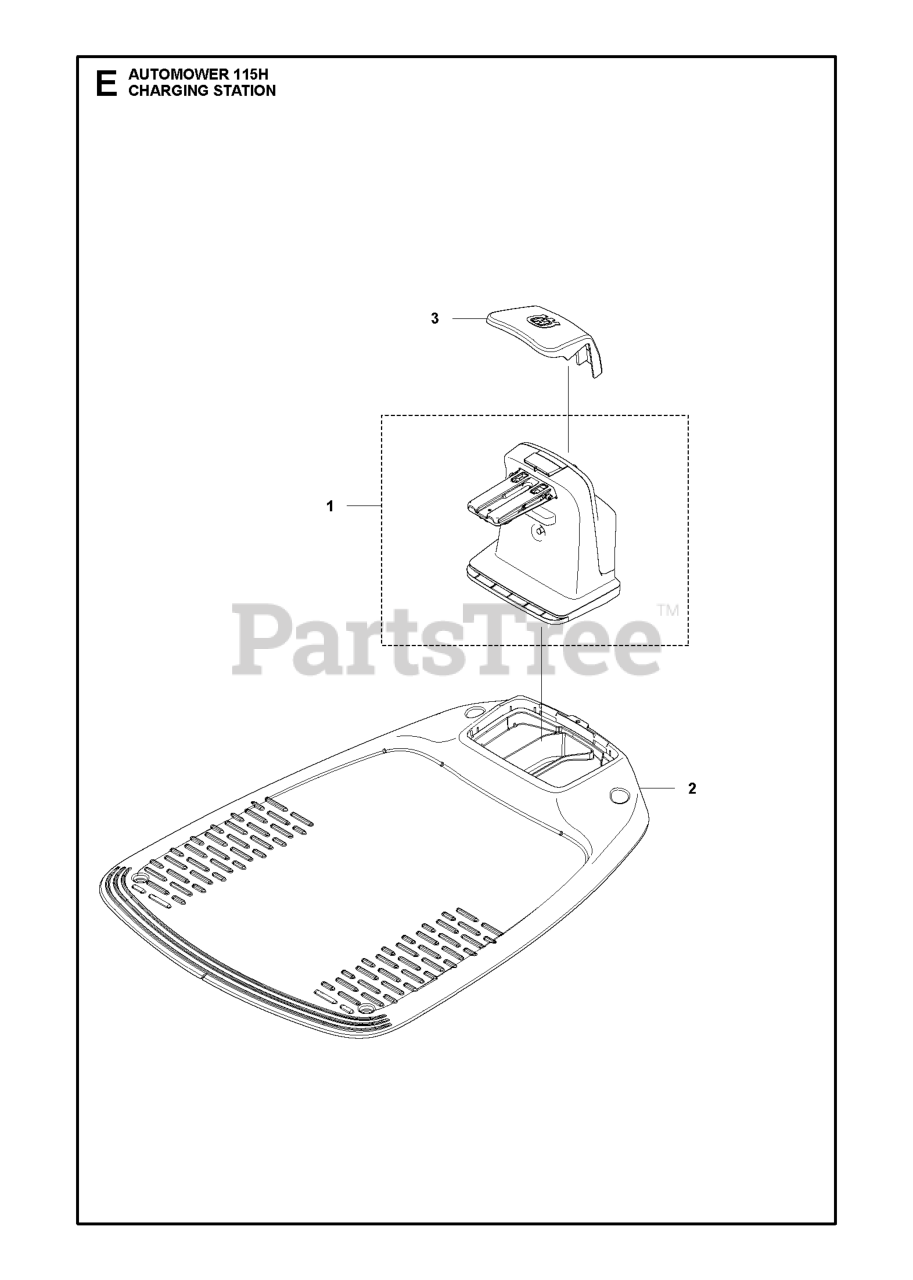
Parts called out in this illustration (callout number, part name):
1	CHARGING TOWER
2	PLATE
3	CAP CHARGING STATION
